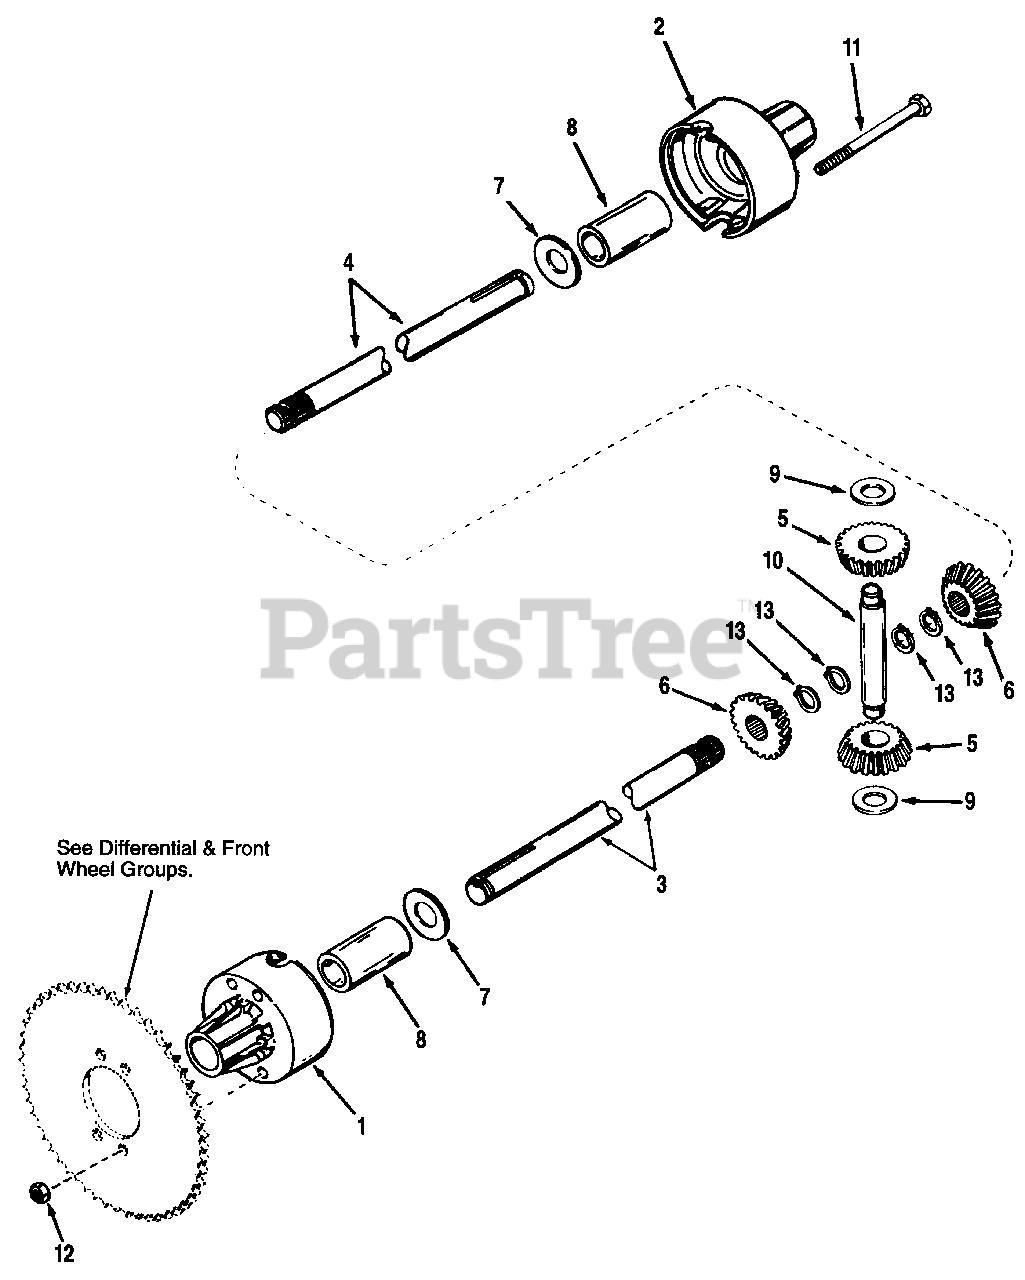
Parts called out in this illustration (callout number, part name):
1	HOUSING, Differential Carrier (Incl. Ref. No. 8)
2	HOUSING, Differential Carrier (Incl. Ref. No. 8)
3	AXLE, 20-3/16" Long
4	AXLE, 8-1/32" Long
5	GEAR, Pinion, 16 Tooth
6	GEAR, Bevel, 16 Tooth
9	WASHER, Thrust
10	PIN, Drive
11	SCREW, Hex, Flanged Hd., 5/16-18 x 3-15/16
12	NUT, Lock, 5/16-18
13	RING, Snap (Pkg. of 2)
